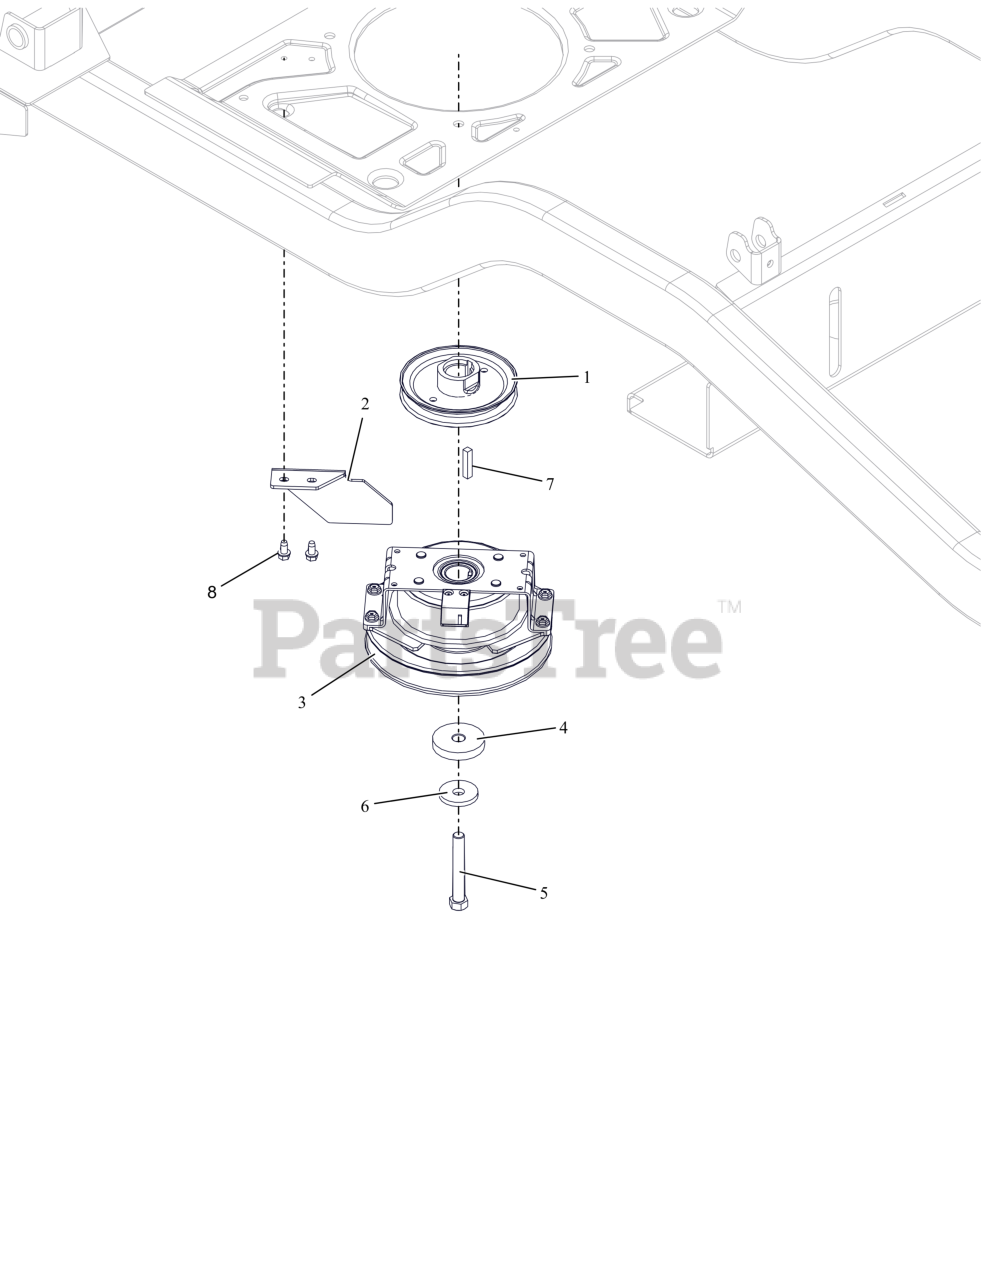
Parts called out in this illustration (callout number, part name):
1	WLDMT,PULLEY-4.50ODX1.003
2	BRKT, CLUTCH STOP HD
3	CLUTCH, OGURA DBL SPRG
4	SPACER, .474/.459X2.00X.350
5	BLT, HEX .44-20X3.00 G8 ZCC NT
6	WASHER, 7/16" SPRING DISK
7	KEY-SQ .25 X 1.25 X .25 SAE
8	SCR-TAP .25-20X.50 HWH ZCC
